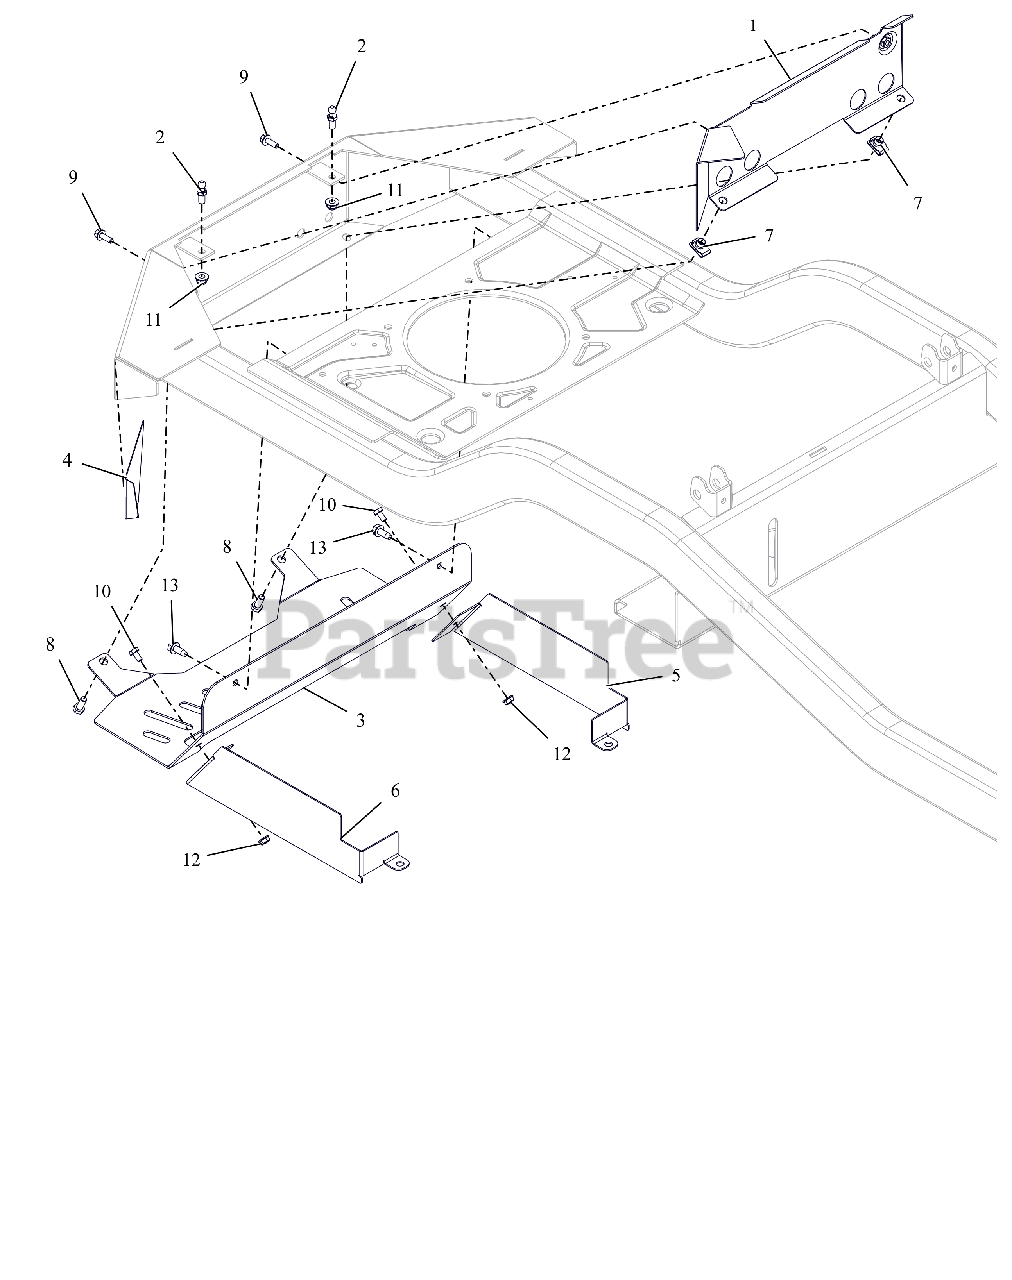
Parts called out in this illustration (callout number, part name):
1	WMT, HEAT BAFFLE
2	STUD- BALL
3	SHIELD, HEAT (HD)
4	TAPE, HEAT DEFLECTOR
5	GUARD,REAR CLUTCH LH
6	GUARD,REAR CLUTCH RH
7	NUT-CLIP RETAINER 5/16-18X.56
8	BLT,HEX .31-18X.75 G5 ZCC
9	BLT,HEX-FLG .25-20X.75 G5 BFP
10	BLT,HEX .25-20X.50 G5 ZCC
11	NUT,LK-NYL-FLG .31-18 G5ZC120
12	NUT-LK-TOP-FLG .250-20 GF ZCC
13	SCR,TAP .312-18X.75 HWH TR ZCC
